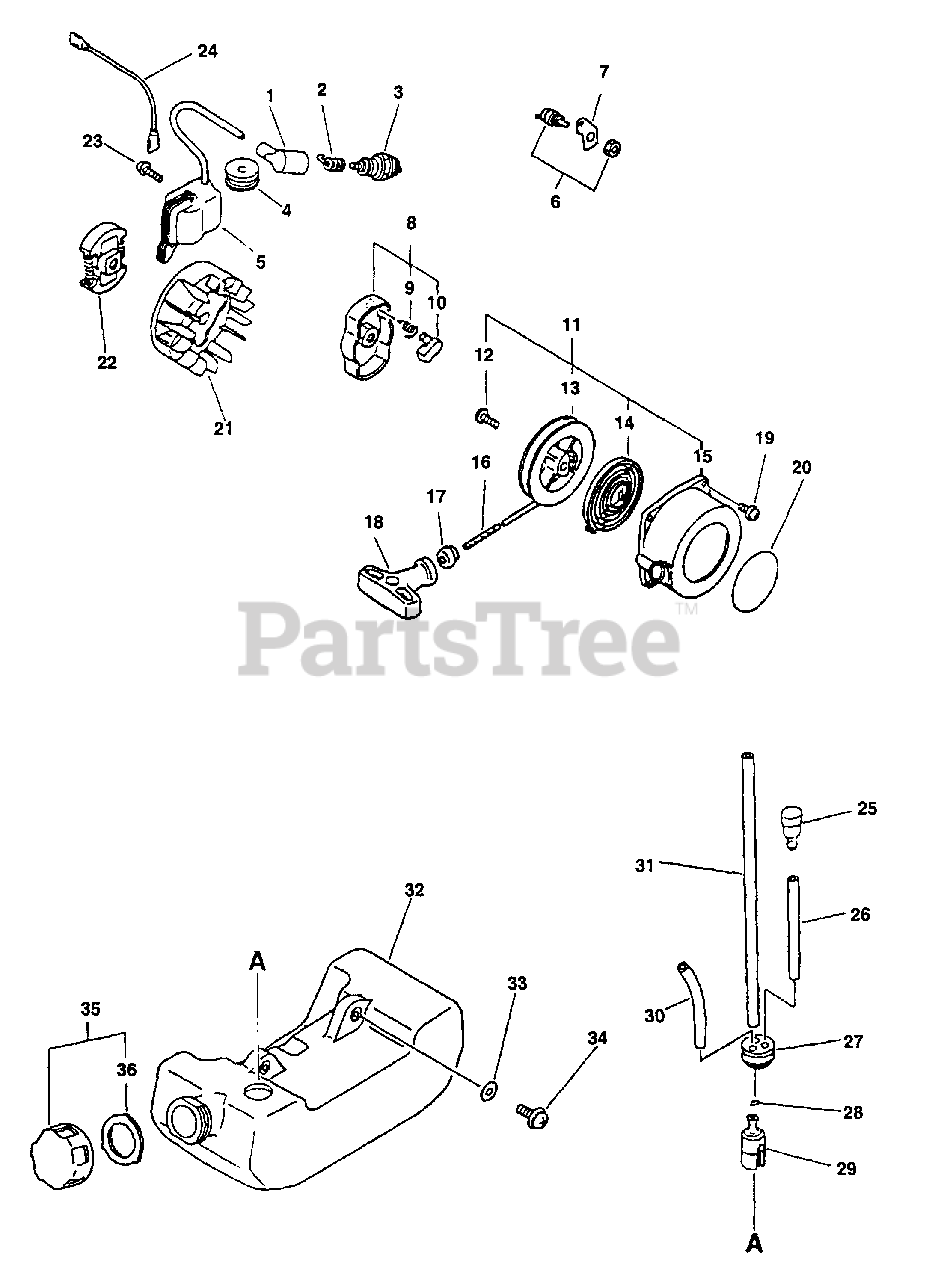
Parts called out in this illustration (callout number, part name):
1	CAP, SPARK PLUG
2	TERMINAL, SPARK PLUG CAP
3	SPARK PLUG -- BPM-7A
3	SPARK PLUG -- BPMR-7A
4	GROMMET
5	COIL, IGNITION
6	IGNITION SWITCH ASSY
7	BRACKET, SWITCH
8	STARTER PAWL ASSY
9	SPRING, RETURN
10	PAWL, STARTER - BLACK
11	STARTER ASSY
13	REEL, ROPE
14	SPRING, REWIND
15	CASE, STARTER
16	ROPE, STARTER
17	GUIDE, ROPE
18	GRIP, STARTER
19	SCREW - 4X16
20	LABEL - ECHO
21	FLYWHEEL
22	CLUTCH ASSY
23	SCREW - 4X22
24	LEAD - GROUND
25	VENT, FUEL TANK
26	PIPE - 3X5X70 -- BLACK
27	GROMMET
28	CLIP - 6
29	FILTER, FUEL
30	PIPE - 3X6X80 -- CLEAR
31	PIPE - 3X5X180 -- BLACK
32	FUEL TANK ASSY
33	WASHER - 5
34	SCREW - 5X16
35	CAP ASSY
36	GASKET, CAP
